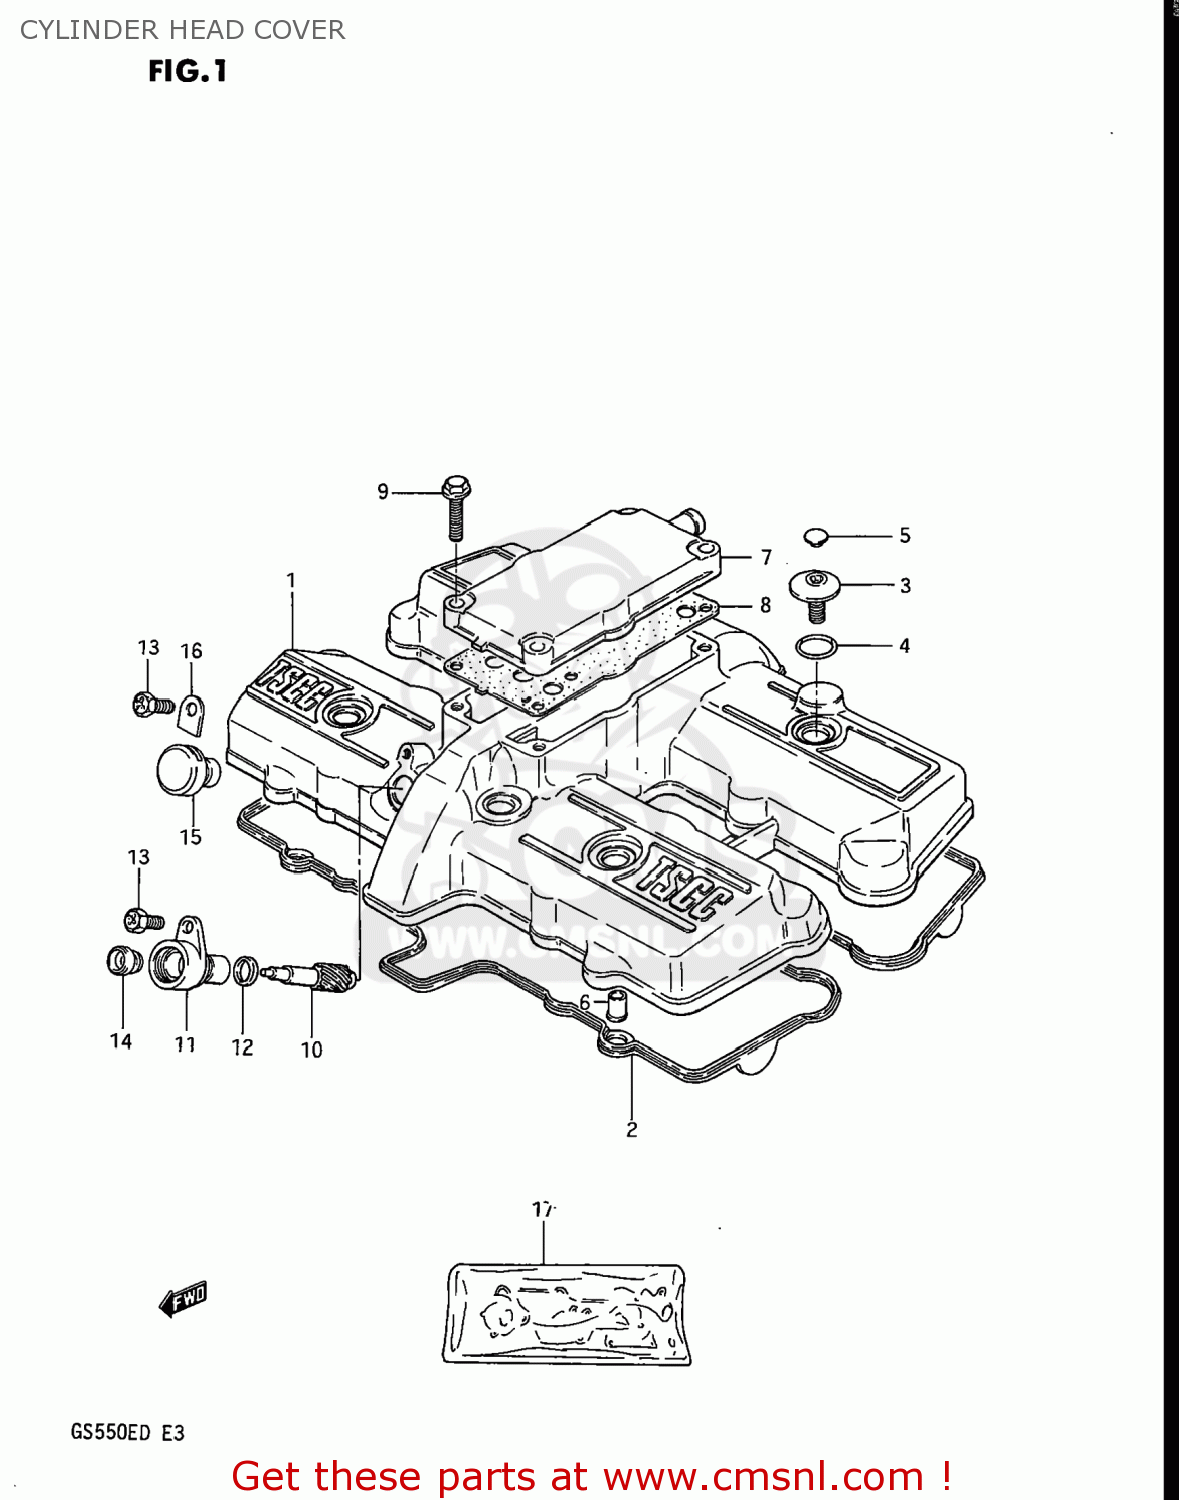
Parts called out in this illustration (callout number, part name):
1	COVER,CYLINDER HEAD
2	GASKET,CYL HEAD COVER (NAS)
3	BOLT(7X5.5)
4	O RING(D:1.9,ID:14.5)
5	CAP(OD:10)
6	PIN
7	COVER,BREATHER
8	GASKET (MCA)
9	BOLT
10	GEAR,TACHOMETER DRIVEN
11	SLEEVE,TACHOMETER DRIVE GEAR
12	SEAL,TACHOMETER DRIVEN
13	SCREW(5X12)
14	SEAL,OIL(5X12X8)
15	PLUG,TACH GEAR SLEEVE HOLE
16	PLATE,TACH DRIVE GEAR SLEEVE
17	GASKET SET (MCA)
